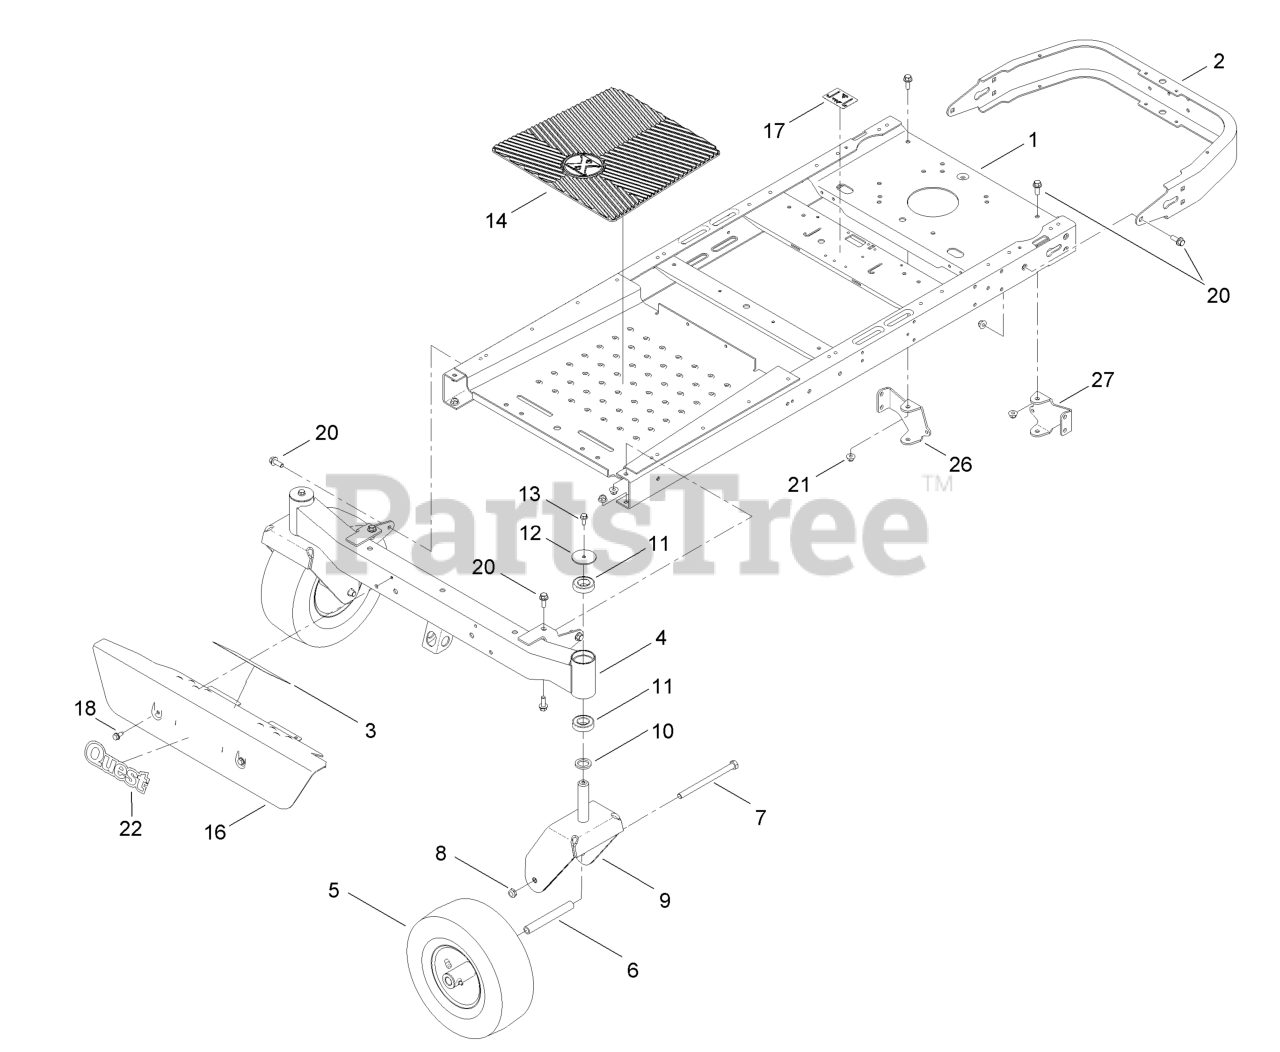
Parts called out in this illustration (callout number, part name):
1	FRAME ASM
2	BUMPER-REAR (WIDE)
4	AXLE-FRONT, WIDE
5	13 INCH WHEEL AND TIRE AS
6	SPANNER
7	WASHER-LOCK
8	NUT-HEX
9	FORK-CASTER
10	WASHER-THRUST
11	BEARING-BALL
13	SCREW-HHF
14	MAT-FLOOR
17	DECAL-TRANSPORT
18	Screw-HWH 5/16-18 X 3/4 Tf
20	SCREW-HHF 3/8-16 X 1
21	NUT-HF, NI
26	MOUNT-HYDRO, REAR (RH)
27	MOUNT-HYDRO, REAR (LH)
